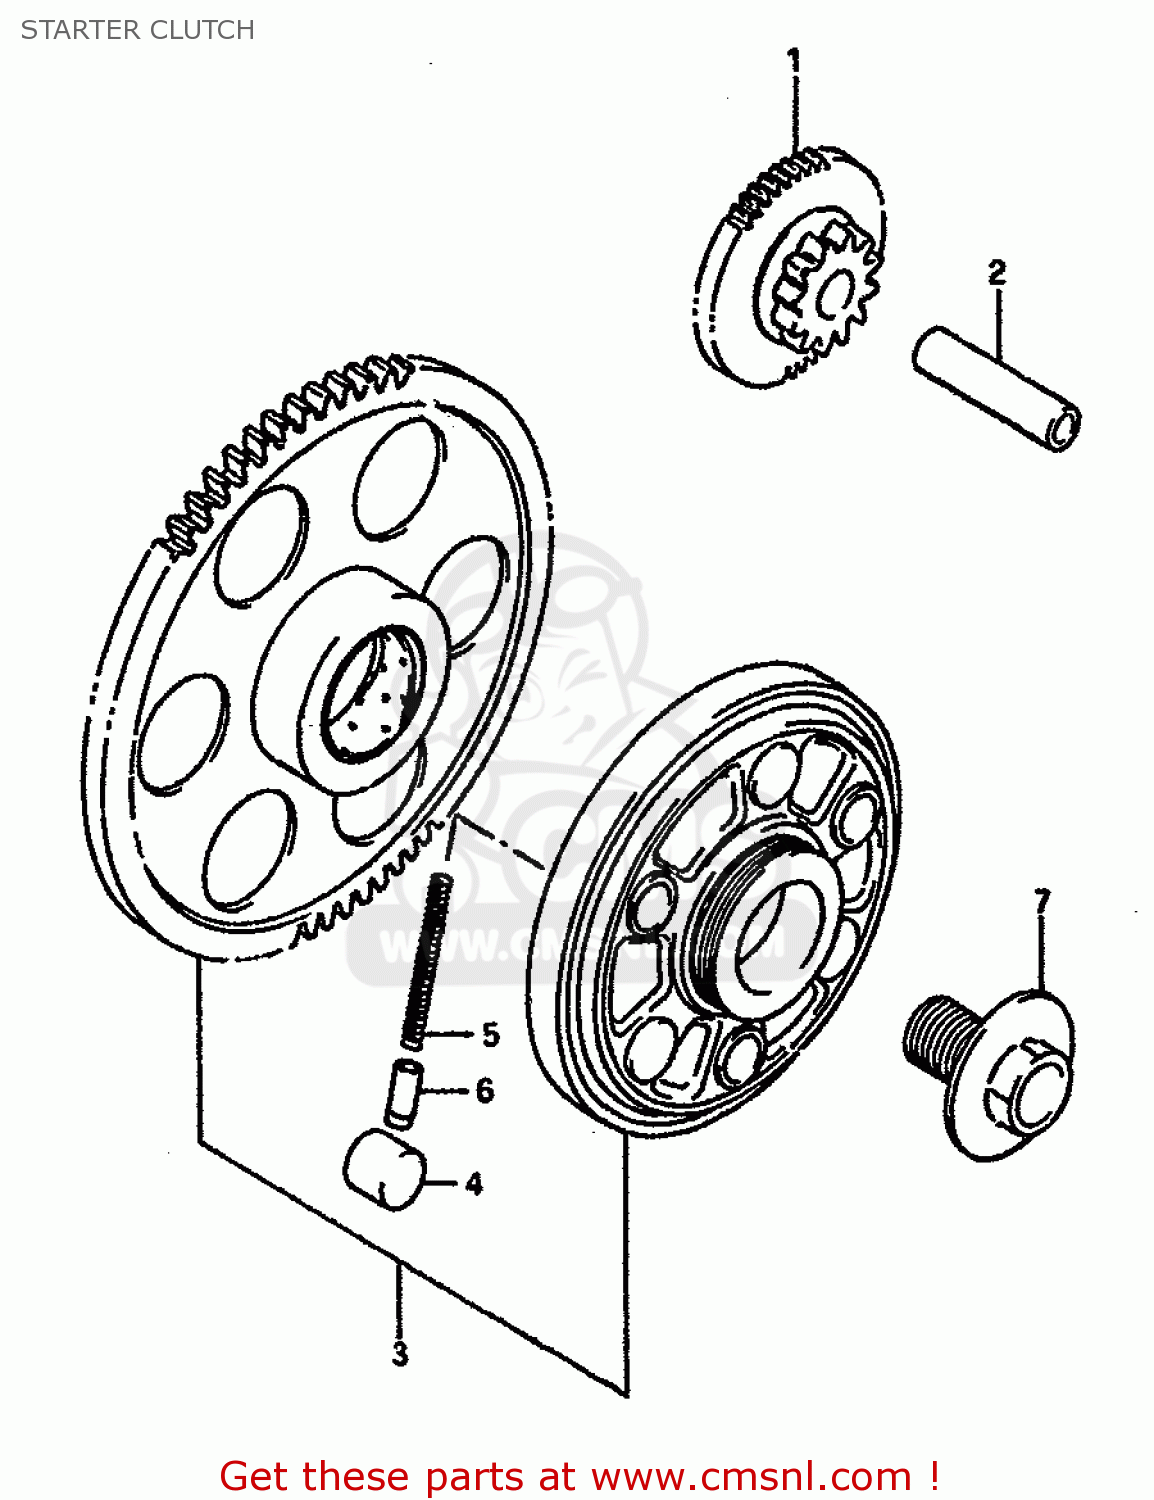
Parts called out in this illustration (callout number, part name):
1	GEAR,STARTER IDLE
2	PIN(7X11X42)
3	CLUTCH SET,STARTER
4	PIN(14X13)
5	SPRING
6	PIECE,PUSH
7	BOLT(14X21)
